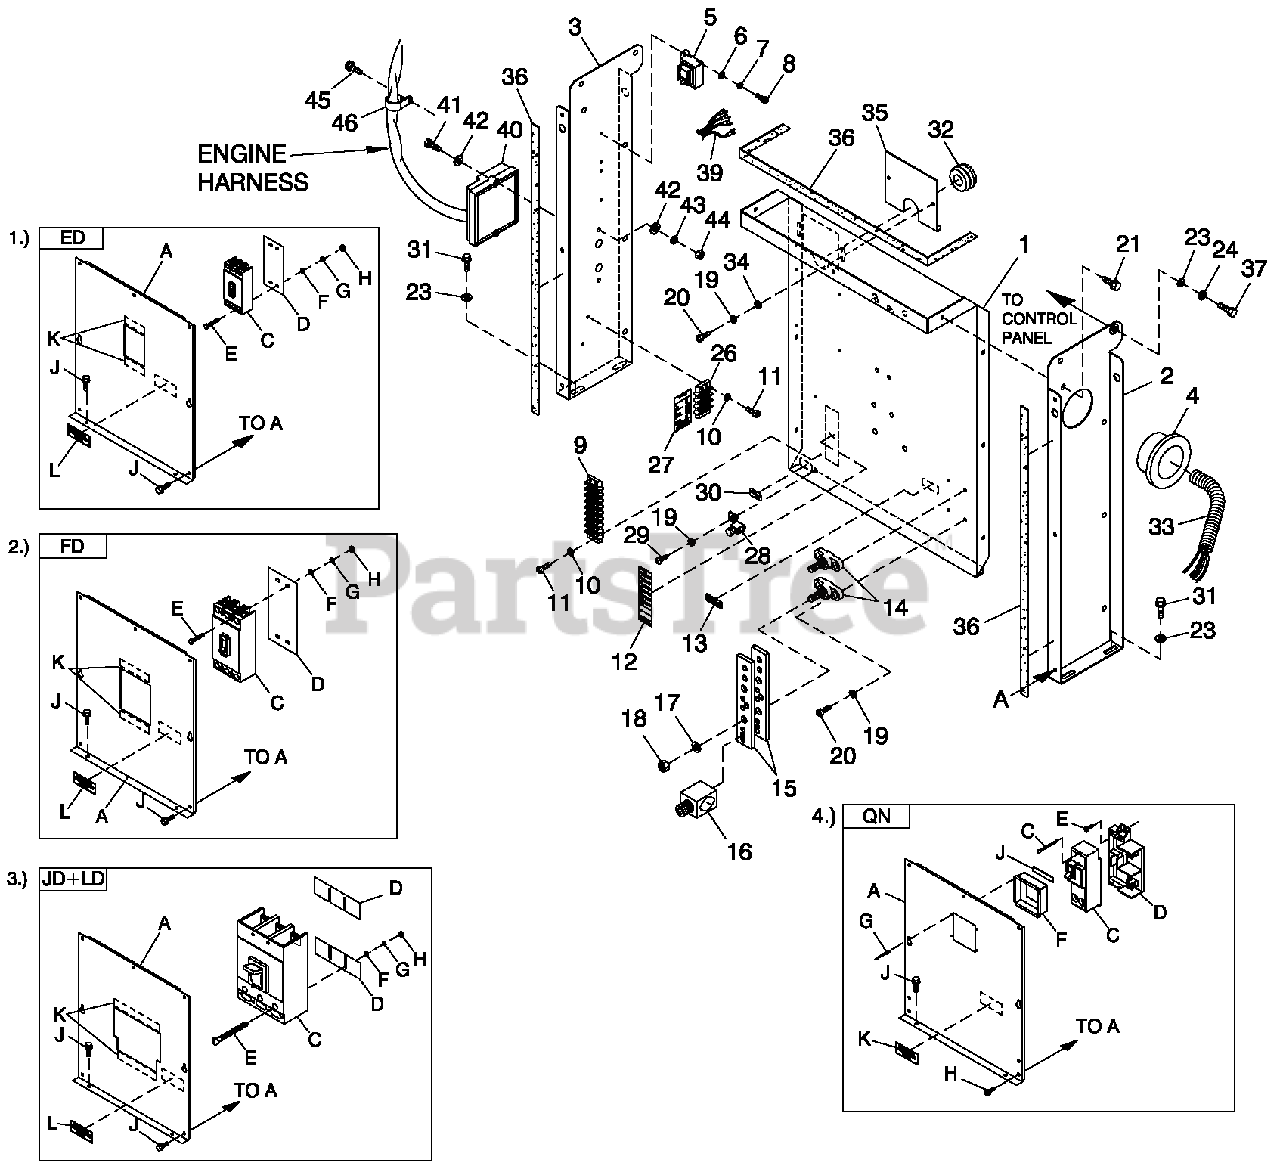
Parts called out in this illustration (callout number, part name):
1	PAN CB CONN BOX
2	STAND RH CONTROL
3	STAND LH CONTROL
4	BUSHING SNAP SB-2.5-31
5	XFMR DUAL 120V/16V (FOR 120/240V & 277/480V UNITS)
6	WASHER FLAT M4
7	WASHER LOCK #8-M4
8	SCRE PHTT M4-0.7 X 10 ZYC
9	BLOCK TERM 20 A8 X 6 X 1100V
10	WASHER LOCK #6
11	SCREW PHTT #6-32 X 1/2 ZYC
12	DECAL UTL SENSE/CUST CONN
13	DECAL NEUTRAL
14	JUNCTION BLO C K 3/8-16
15	BUS BAR NEUTRAL BLOCK 390
16	LUG SLDLSS 600/250-1/0 X 1/4-28
17	WASHER LOCK 3/8
18	NUT HEX 3/8-16 STEEL
19	WASHER LOCK M5
20	SCREW PHTT M5-0.8 X 1 6 ZYC
21	SCREW THF M6-1 X 16N WA Z /JS
23	WASHER FLA T 1/4-M6 ZINC
24	WASHER LOCK M6-1/4
26	BLOCK TERM 20 A6 X 3 X 1100V
27	DECAL CUST CONN 120V UTILITY
28	LUG SLDLSS # 6 14 X 13 /64 CU
29	SCREW HHTT #10-32 X 3 /8 CZ
30	DECAL GROUND LUG
31	SCREW HHTT M6-1.0 X 16 ZYC
32	GROMMET 1.25X .25 X .75
33	CONDUIT FLEX 2 .0 ' ID (36" LG)
34	WASHER FLAT M5
35	PLATE WIRE SNGL GALV
36	TAPE ELEC 1/2 FOAM (AS REQ'D)
37	SCREW HHC M 6-1.0X 16G 8.8
39	HARNESS, TRANSFORMER ADAPTER
40	ASSY ENCLOSURE PCB 4.2L IGN MD
41	SCREW PPHM # 10/32 X 2
42	WASHER FLAT # 10 ZINC
43	WASHER LOCK #10
44	NUT HEX #10-32 STEEL
45	SCREW THF M6-1 X 16 N WAZ /JS
46	CLAMP VINYL 1.06 X .406 Z
47	SEAL WEATHER .45" DIA
A	COVER ED CB SHORT STND
C	CB0050A 3P 480V S ED4 LL
D	INSULATOR CB S (ED-3 P)
E	SCREW RHM # 10 -3 2X 4 -1 /2
F	WASHER FLA T # 10 ZINC
G	WASHER LOCK #10
H	NUT HEX #10-32 STEEL
J	SCREW THF M6-1 X 16 N WA Z/J S
K	TAPE ELEC 1/2 FOAM (AS REQ 'D)
L	DECAL CUSTOMER CONNECT INSIDE
A	COVER CB CONN BOX
C	CB 0150A 3P 600V S FD6LL
D	INSULATOR CB FD FRAME 30ML
E	SCREW SHC 1/4 -20 X 4.5 G8.8 NZ
F	WASHER FLAT 1/4-M6 ZINC
G	WASHER LOCK M6. 1/4
H	NUT HEX 1/4-20S TEE L
J	SCREW THF M6-1 X 16 N WAZ /JS
K	TAPE ELEC 1/2 FOAM (AS REQ'D)
A	COVER JD/LD CB SHRT STAND
C	CB 0300A 3P 600V S JD6LL
D	INSULATOR CIRCUIT BR. JD/LD
E	SCREW RHM 1/4-20 X 3
G	WASHER LOCK M6-1/4
H	NUT HEX 1/4-20 STEEL
A	COVER QN FRM CB
C	CB 0150A 2P 240V S QN2LL
D	BASE, QN CIRCUIT BREAKER
E	SCREW HHTT M5 -0.8 X 10 BP
F	COVER QN CB DISH
G	RIVET POP .125 X .275 SS
H	SCREW THF M 6-1X16 N WA Z/JS
J	TAPE ELEC 1/2 FOAM (AS REQ'D)
K	DECAL CUSTOMER CONNECT INSIDE
